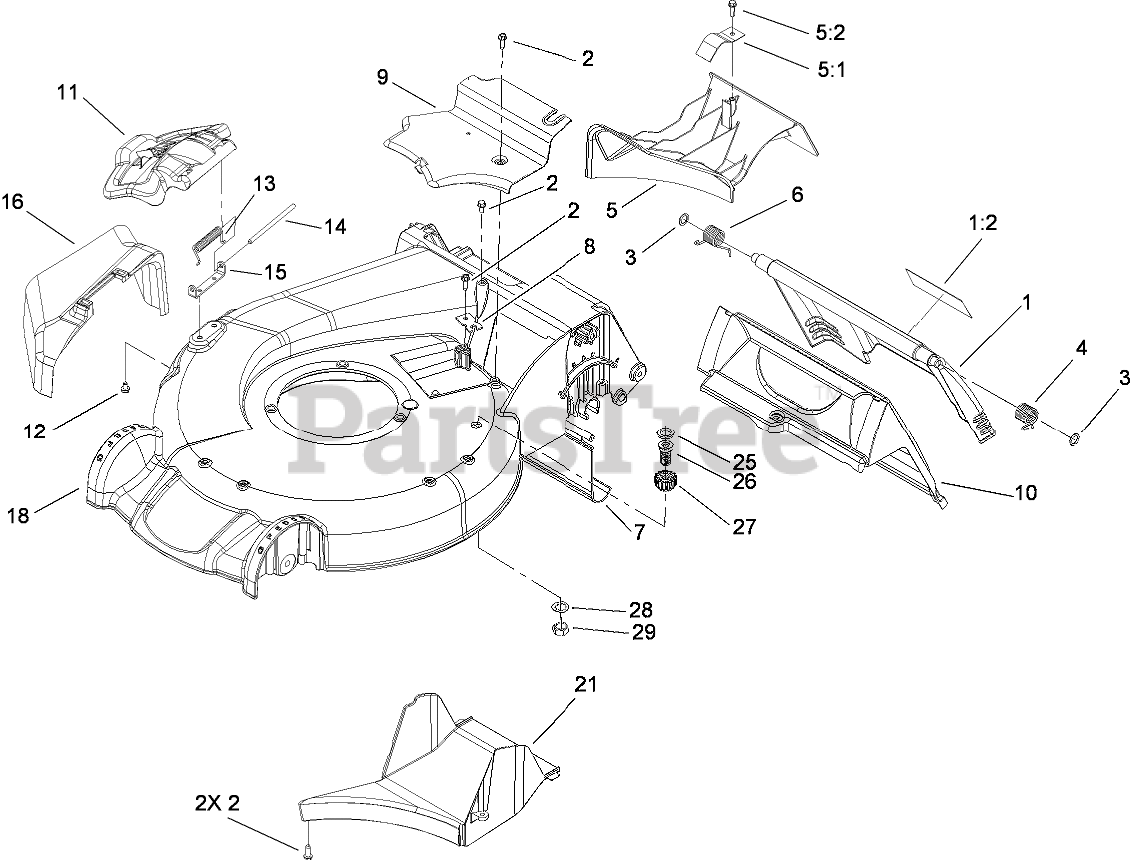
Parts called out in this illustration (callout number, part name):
1	REAR DOOR ASM
1:2	DECAL-WARNING
2	SCREW-HWHTF
3	WASHER-NYLON
4	SPRING-TORSION
5	PLUG-MULCH ASM
5:1	TAB-SPRING
5:2	SCREW-HWH
6	SPRING-TORSION
7	SHIELD-TRAILING
8	BRACKET-CABLE, TRACTION
9	COVER-BELT
11	DISCHARGE DOOR ASM
12	SCREW-HWH
13	SPRING-TORSION
14	ROD-COVER
15	BRACKET-COVER
16	CHUTE-DISCHARGE, SIDE
18	HOUSING ASM
21	TUNNEL-DISCHARGE
25	WASHER-SEAL, WASHOUT PORT
26	PORT-WASHOUT
27	COUPLING-HOSE, WASHOUT PORT
28	WASHER-TOOTH, INTERNAL
29	NUT-JAM
